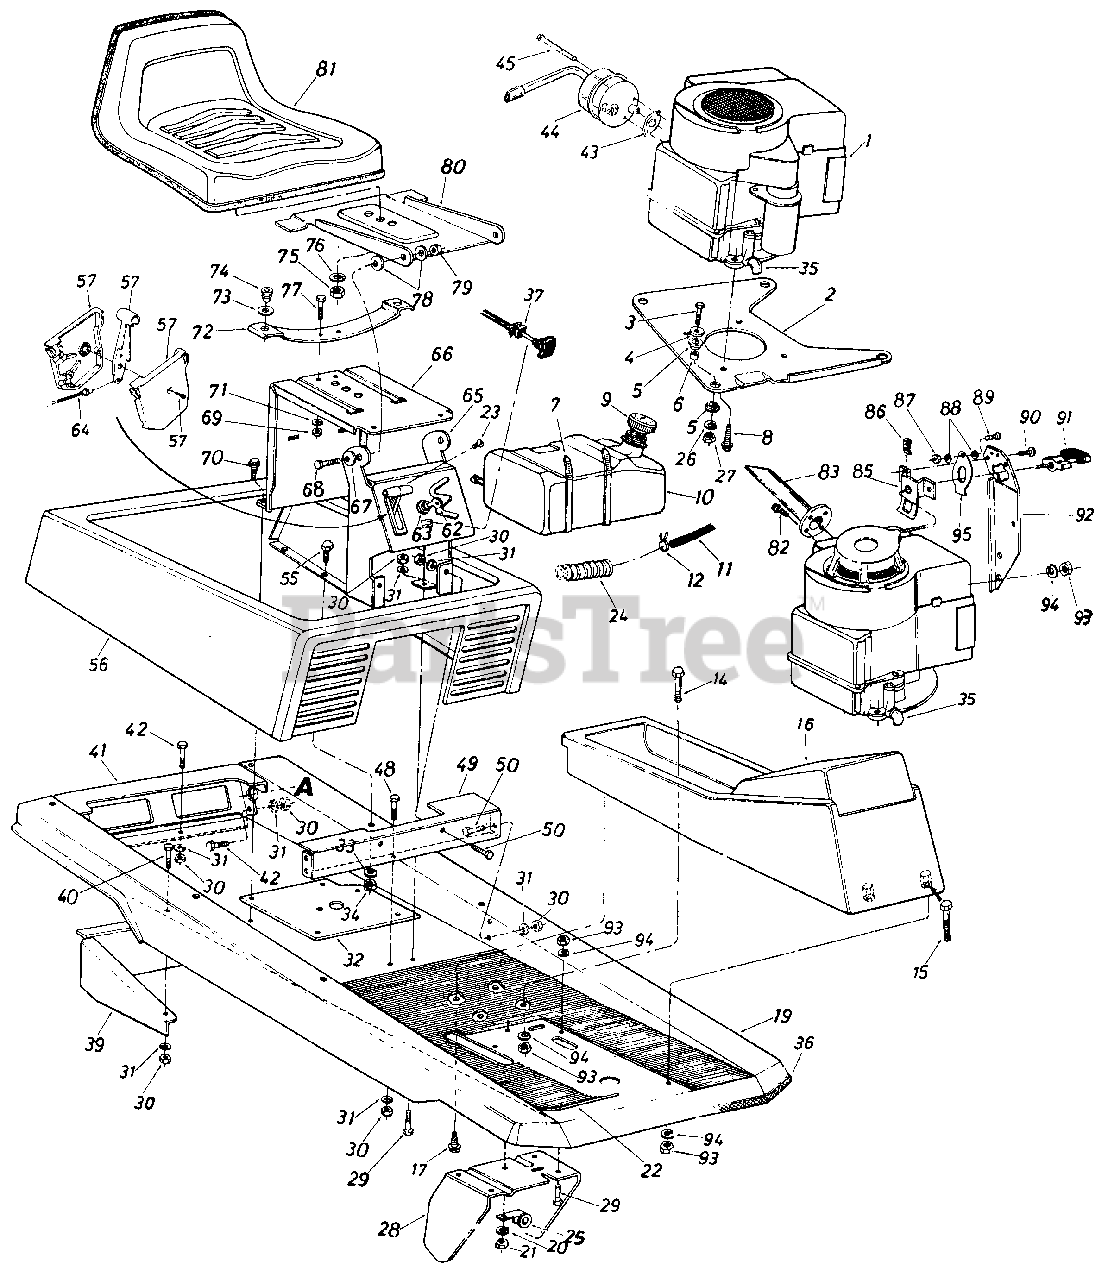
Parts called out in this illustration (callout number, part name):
2	PLATE-ENGINE MTG
3	SCREW-HEX 5/16-24 X 1.25
4	WASHER-FL-.312 X 1.125 X .125
5	MOUNT-ENGINE
6	SPACER
7	TIE-CABLE
8	SCREW-HEX SLF TAP 3/8 X 1 3/8
9	GAUGE-GAS
10	TANK-GAS
11	FUEL LINE-15IN
12	CLAMP-HOSE
14	SCREW-HEX 5/16-18 X 1.75
15	SCREW-HEX 5/16-18 X 2.00
16	CONSOLE-FR
17	SCREW-PLASTIC-5/16X1.0
20	WASHER-LOCK-5/16
21	NUT-HEX 5/16-18
22	MAT-FLOOR
23	SCREW-TRUSS TAP
24	CONDUIT-CONVOLUTED
26	WASHER-LOCK-5/16
27	NUT-5/16-24
28	PEDAL ASSY-BRAKE
29	SCREW-HEX 5/16-18 X .75
30	NUT-HEX 5/16-18
31	WASHER-LOCK-5/16
32	BRACKET-VAR SP MTG
33	LOCK WASHER 1/4 DIA
34	NUT-HEX 1/4-20
36	STRIP-TRIM-12IN
37	CONTROL-CHOKE
39	SUPPORT ASSY-TRANS
40	SCREW-HEX 5/16-18 X .75
43	GASKET-EXHAUST
44	MUFFLER
45	BOLT-SHD 3/8
49	BRACKET-SEAT SUP
50	SCREW-HEX 5/16-18 X .75
55	Hex Bolt
56	COVER ASSY
57	CONTROL-THROTTLE
62	KEY-IGN (SET OF TWO)
63	SWITCH-IGNITION
64	CABLE-THROTTLE
65	BRACKET-SEAT
66	KIT-SEAT BRKT ASSY
67	WASHER-BELL .337 X .867 X .057
68	SCREW-HEX 5/16-18 X .75
69	NUT-HEX 5/16-18
70	SCREW-HEX WASH SF TAPP
71	L-WASH. 1/4" I.D.
72	SPRING-SEAT
73	WASHER-FL-.531 X .930 OD X .050
75	NUT-HEX 1/2-13
76	WASHER-LOCK-1/2
77	SCREW-HEX 5/16-18 X .75
78	WASHER-BELL .337 X .867 X .057
79	NUT-HEX CENTER L-5/16-18
80	BRACKET-SEAT PIVOT
81	SEAT
82	SCREW-HEX HD IND
83	PIPE ASSY-EXHAUST
85	BRACKET ASSY-SWITCH
86	NUT-SPEED-10-24
88	WASHER-FIBER
89	SCREW-TRUSS MACH
90	SCREW-TRUSS MACH
91	HANDLE-PLASTIC
92	BRACKET-ROPE HDLE
93	NUT-HEX 5/16-18
94	WASHER-LOCK-5/16
95	SPRING-SWITCH
